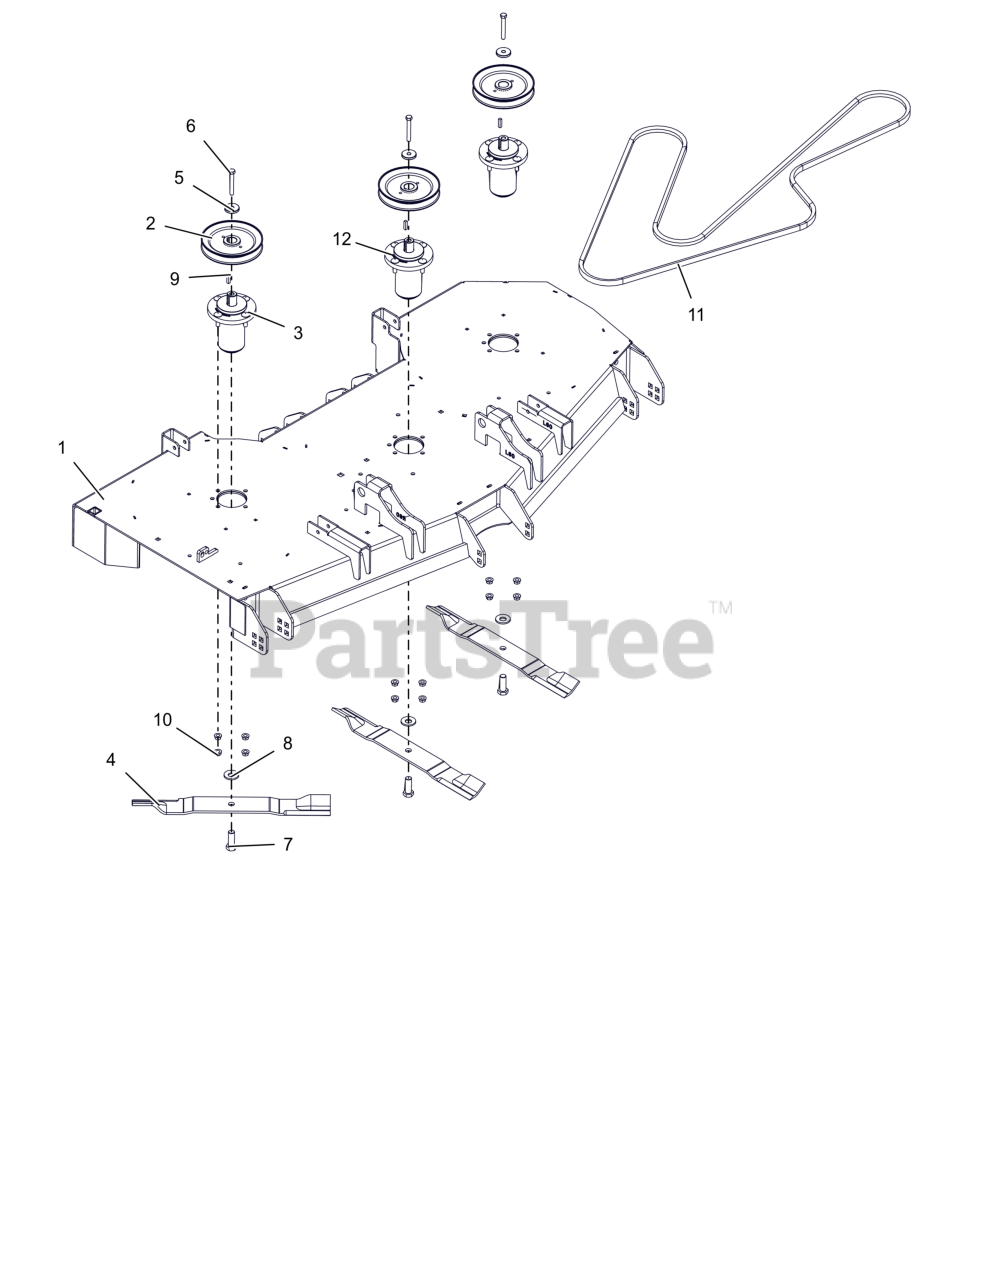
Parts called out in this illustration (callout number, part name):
1	KIT- SERVICE 60" DECK W/DECALS
2	PULLY, 1.00 ID X 6.34
3	ASM, ALUM SPINDLE
4	BLADE, MOWER (20.50")
5	RETAINER, SHEAVE
6	BLT, HEX .38-16X2.75 G8 ZCC
7	BLT, HEX .62-18X1.75 G8 ZCC
8	WSHR-BLVL .669X1.535X.138
9	KEY, SQ .25X.25X1.00 RC 40-50
10	NUT-LK-CTR-FLG .375-16 GF ZCC
11	V-BELT, B RAW EDGE EPDM
12	ASM, MAINT FREE ALUM SPINDLE
